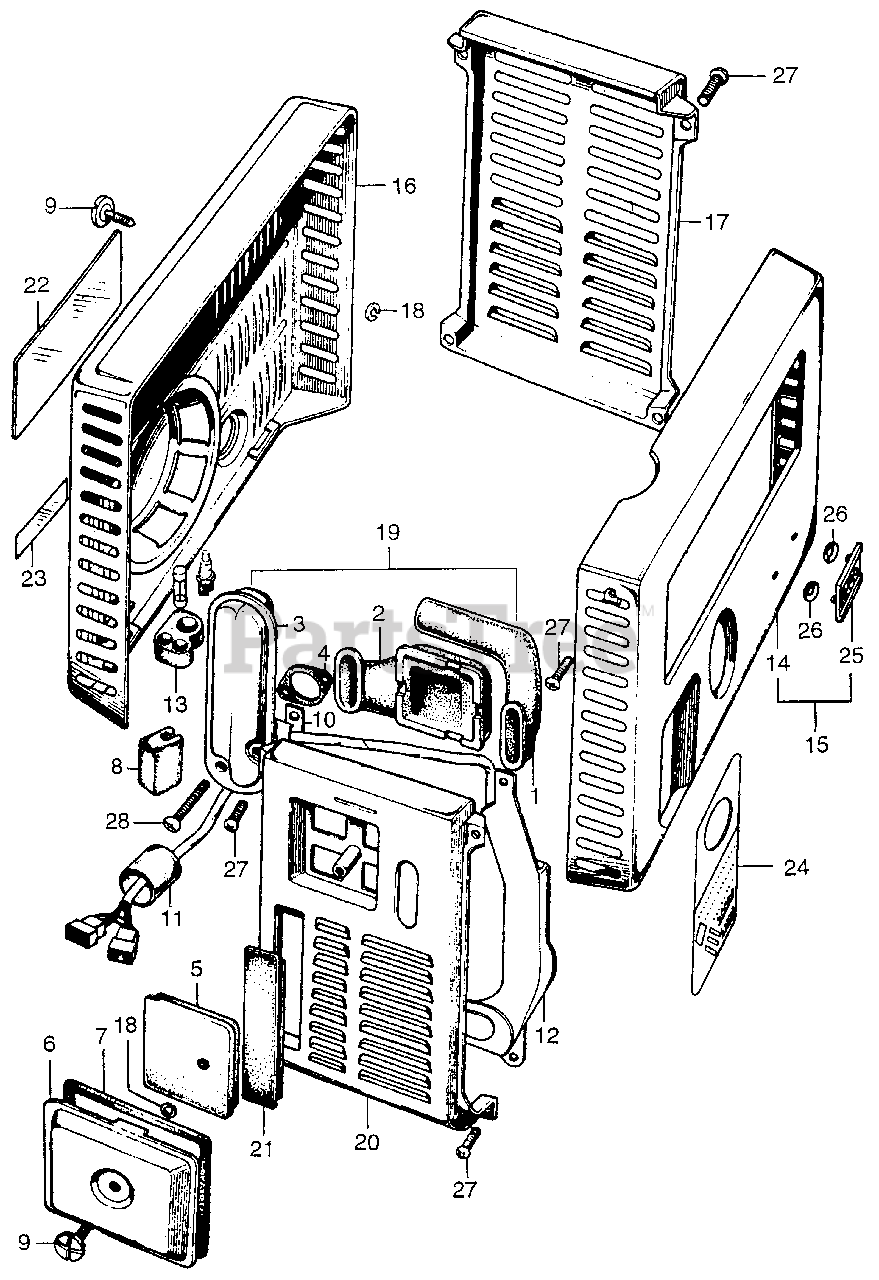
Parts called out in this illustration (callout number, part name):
1	TUBE, AIR CLEANER
1	TUBE, AIR CLEANER (NOT AVAILABLE)
2	TUBE, IN. MUFFLER CONNECTING
3	MUFFLER, IN.
4	GASKET, IN. MUFFLER
5	ELEMENT, AIR CLEANER
6	COVER, AIR CLEANER *NH2M* (METALLIC SILVER) (NOT AVAILABLE)
7	RUBBER, AIR CLEANER SEAL (NOT AVAILABLE)
8	PROTECTOR, CARBURETOR
9	SCREW, COVER LATCH (NOT AVAILABLE)
10	CLAMP, WIRE
11	TUBE, CONNECTOR
12	REGULATOR ASSY., TRANSISTOR (E R400)
13	HOLDER, SPARE PLUG
14	COVER, FR. *Y2C* (CANDY GOLD)
14	COVER, FR. *R15L* (WINE RED)
14	COVER, FR. *G3C* (CANDY CAT'S EYE GREEN) (NOT AVAILABLE)
15	COVER ASSY., FR. *Y2C* (CANDY GOLD)
15	COVER ASSY., FR. *G3C* (CANDY CAT'S EYE GREEN)
16	COVER, RR. *Y2C* (CANDY GOLD) (NOT AVAILABLE)
16	COVER, RR. *R15L* (WINE RED)
16	COVER, RR. *G3C* (CANDY CAT'S EYE GREEN)
17	COVER, R. SIDE *Y3L* (IVORY WHITE)
18	STOPPER, LATCH (NOT AVAILABLE)
19	COVER ASSY., L. SIDE *Y3L* (IVORY WHITE)
20	COVER ASSY., L. SIDE *Y3L* (IVORY WHITE)
21	GROMMET, CHOKE
22	PLATE, CAUTION
23	PLATE, EX. CAUTION
24	MARK, OIL LEVEL
26	NUT, SPEED (3MM)
27	SCREW, PAN (5X10)
28	SCREW, PAN (5X20)
